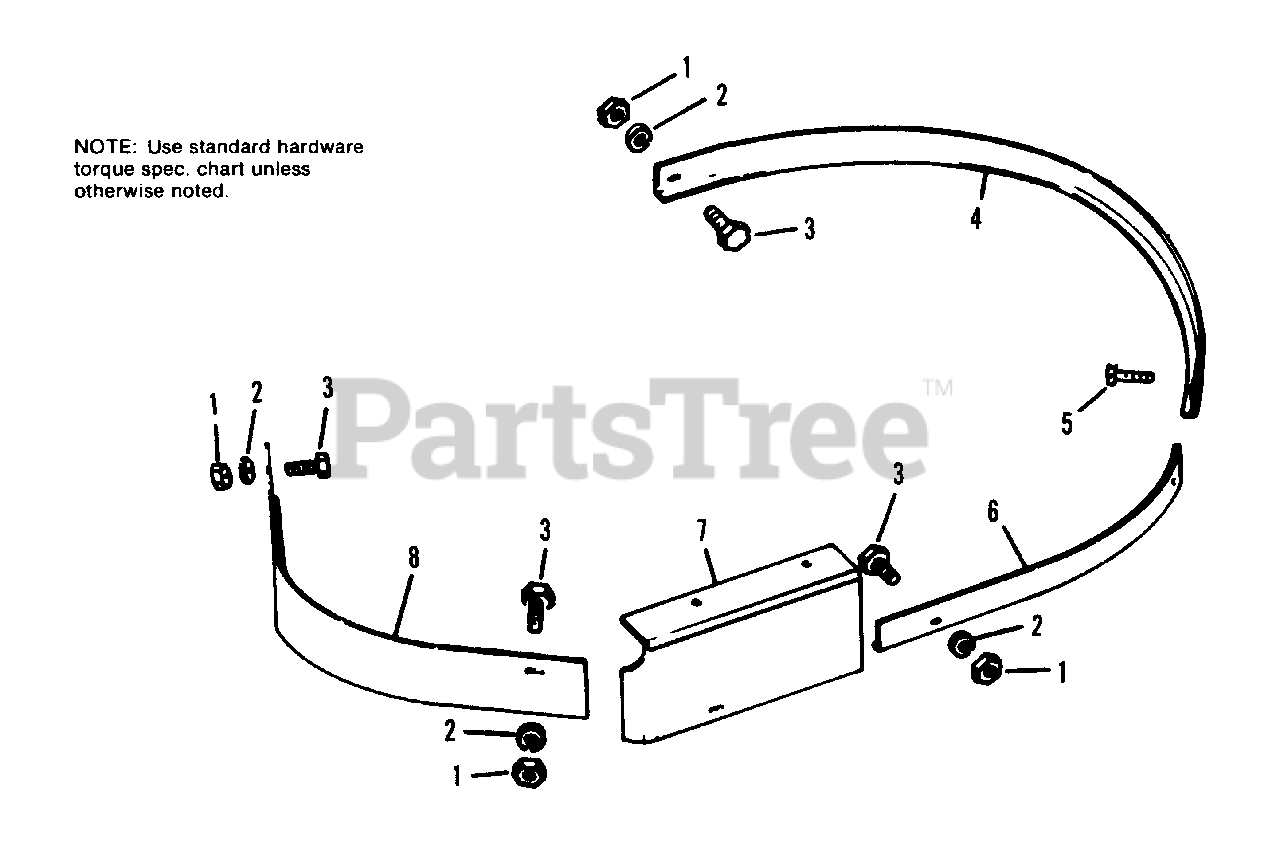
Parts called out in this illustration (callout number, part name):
1	NUT, Hex, Full, 1/4-20
2	LOCKWASHER, 1/4
3	CAPSCREW, Hex Hd., 1/4-20 x 1/2
4	BAFFLE, Rear
5	CAPSCREW, Hex Hd., 1/4-20 x 5/8
6	BAFFLE, Rear, L.H.
7	BAFFLE, Side
8	BAFFLE, Front
